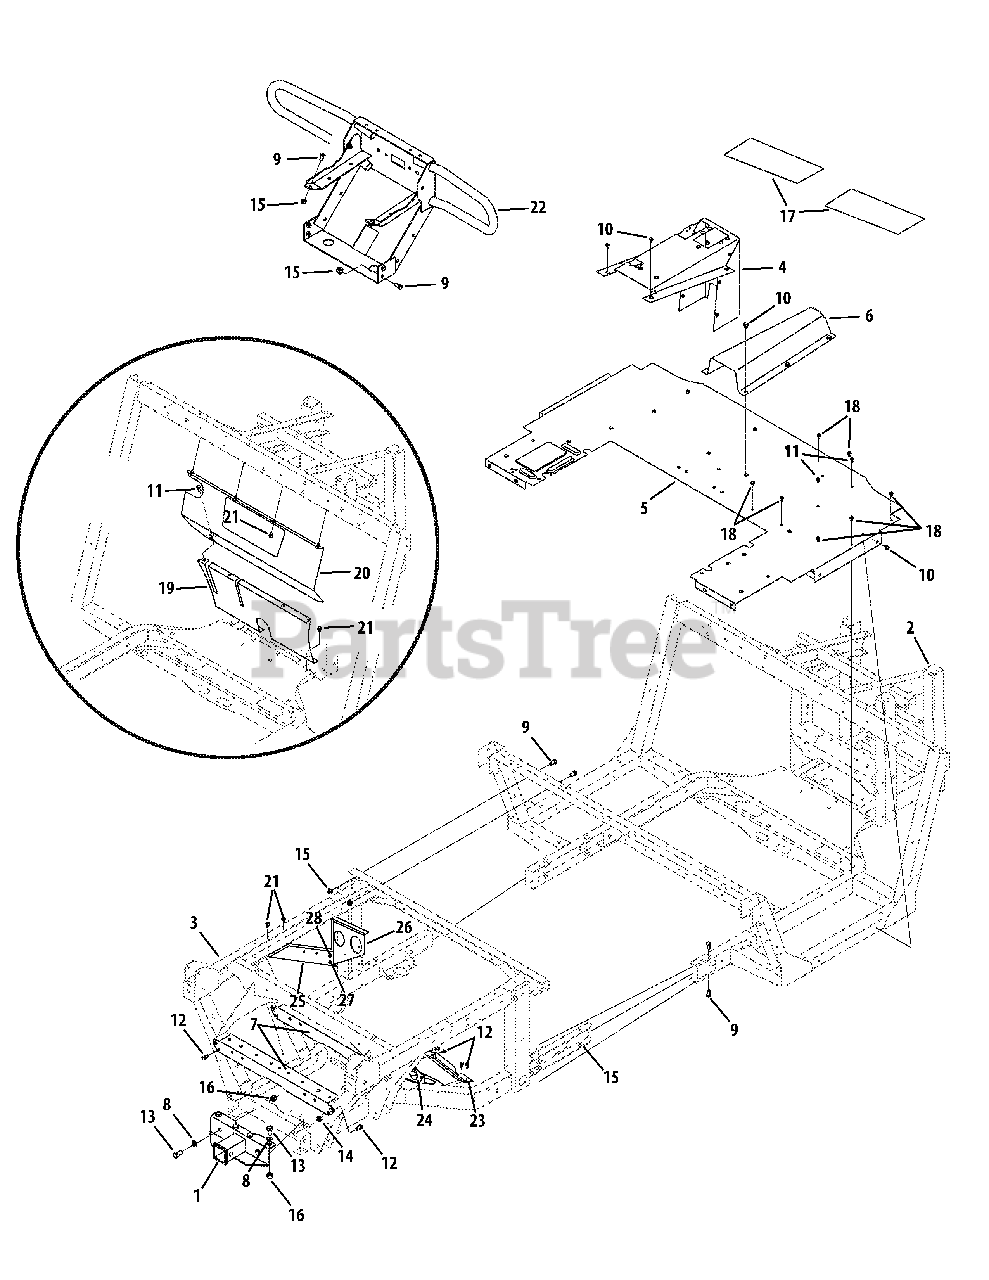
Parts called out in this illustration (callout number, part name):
1	Hitch Assembly, receiver Rr
2	Frm Assembly, front, uv
3	Frm Assembly, rear, uv
4	Plt, cnsol, 4x4
6	Cvr, shf, dr, front, 4x4
7	Chan, support, rear
8	Washer, Flat, .510 x 1.00 x .060
9	Screw, 3/8-16, .75, gr5, std
10	Scr, tt, 5/16-18, 0.500, hxindwsh
11	Scr, ab, 1/4-14, 0.625, trustrxi
12	Screw, hhcs, 5/16-18 (4x2)
12	Screw, Hx flg, 5/16-18 (4x4)
13	Screw, 1/2-13, 1.00, gr5, std
14	Nut, flglk, 5/16-18, grf, nylon
15	Nut, flglk, 3/8-16, grf, nylon
16	Nut, hexlk, 1/2-13, grb, nylon
17	Pad, abrasive, toe Plate
18	Clip, pnl, ret,
19	Pnl, Dash, Lower, 4x4
20	Pnl, Dash, Upper
21	Scr, tt, 1/4-20 x .500
22	Bmpr Assembly, frt.
23	Mt Assm, Sway Bar, RH
27	Hhcs, 1/4-20 x .620
28	Nut, Flglk, 1/4-20
